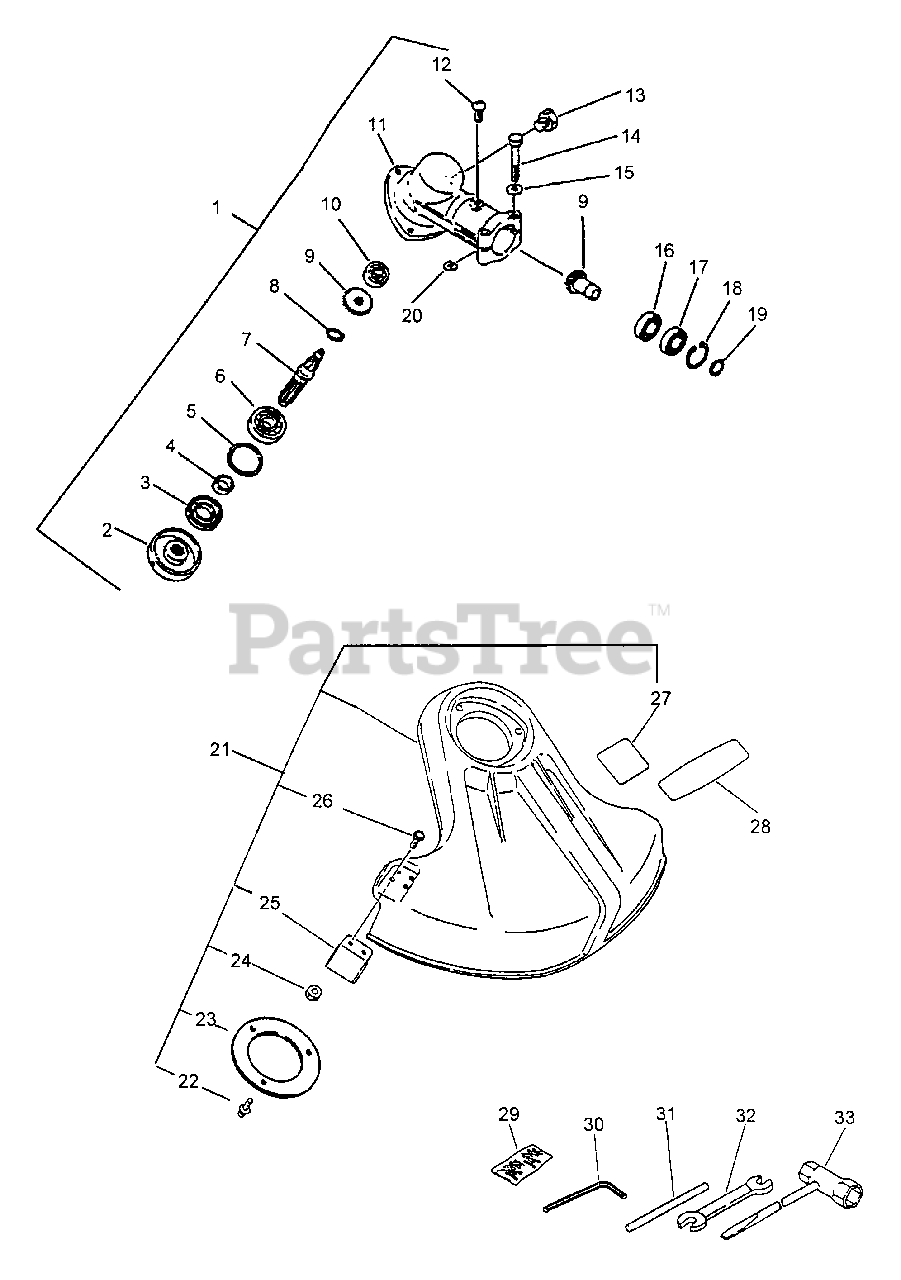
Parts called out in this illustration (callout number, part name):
1	GEAR CASE ASSY
2	ADAPTOR, BLADE - UPPER
3	SEAL, OIL
5	RING, RETAINING - 32
6	BEARING, BALL - 6201
7	GEAR - SHAFT
8	RING, RETAINING - 10
9	GEAR SET - BEVEL
10	BEARING, BALL - 609
11	CASE, GEAR
12	SCREW - 5X10
13	BOLT - 8X8
14	BOLT - 5X35
15	WASHER - 5
16	BEARING, BALL - 6900
17	BEARING, BALL - 6900Z
18	RING, RETAINING - 22
19	RING, RETAINING - 12
21	DEBRIS SHIELD KIT
22	SCREW - 5X18
23	PLATE, SHIELD
25	KNIFE, TRIMMER LINE
26	SCREW - 5X16
27	LABEL - CAUTION
28	LABEL - ECHO
29	PIN, SPLIT - 2X22
30	HEX KEY - 4mm
31	LOCKING TOOL
32	SPANNER - 8X10mm
33	T-WRENCH - 17X19mm
